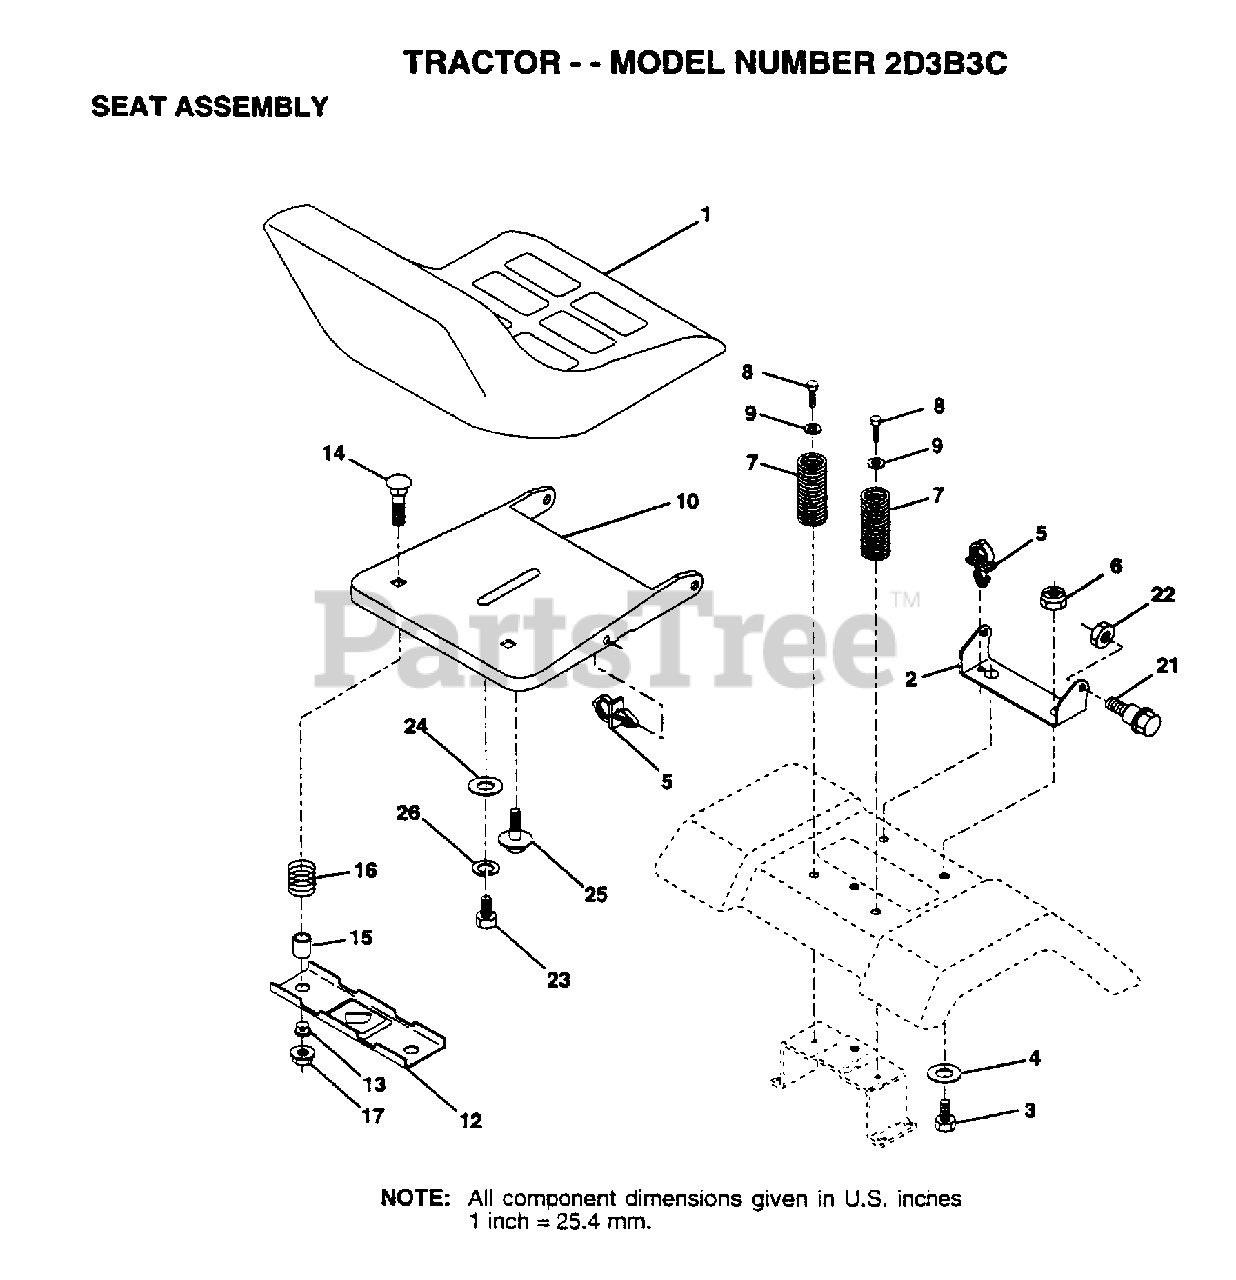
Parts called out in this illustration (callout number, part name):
2	BRACKET PVT SEAT
3	BOLT
4	WASHER PM
5	CLIP.PUSH-IN.HING
6	NUT
7	SPRING COMPRESSIO
8	SCREW GTV
9	WASHER
12	BRKT SWITCH
13	BUSHING
15	SPLIT SPACER
16	SPRING
21	BOLT.SHLD.5/16-18
22	NUT
23	BOLT
24	WASHER
25	"BOLT,SHOULDER"
26	LOCKWASHER
